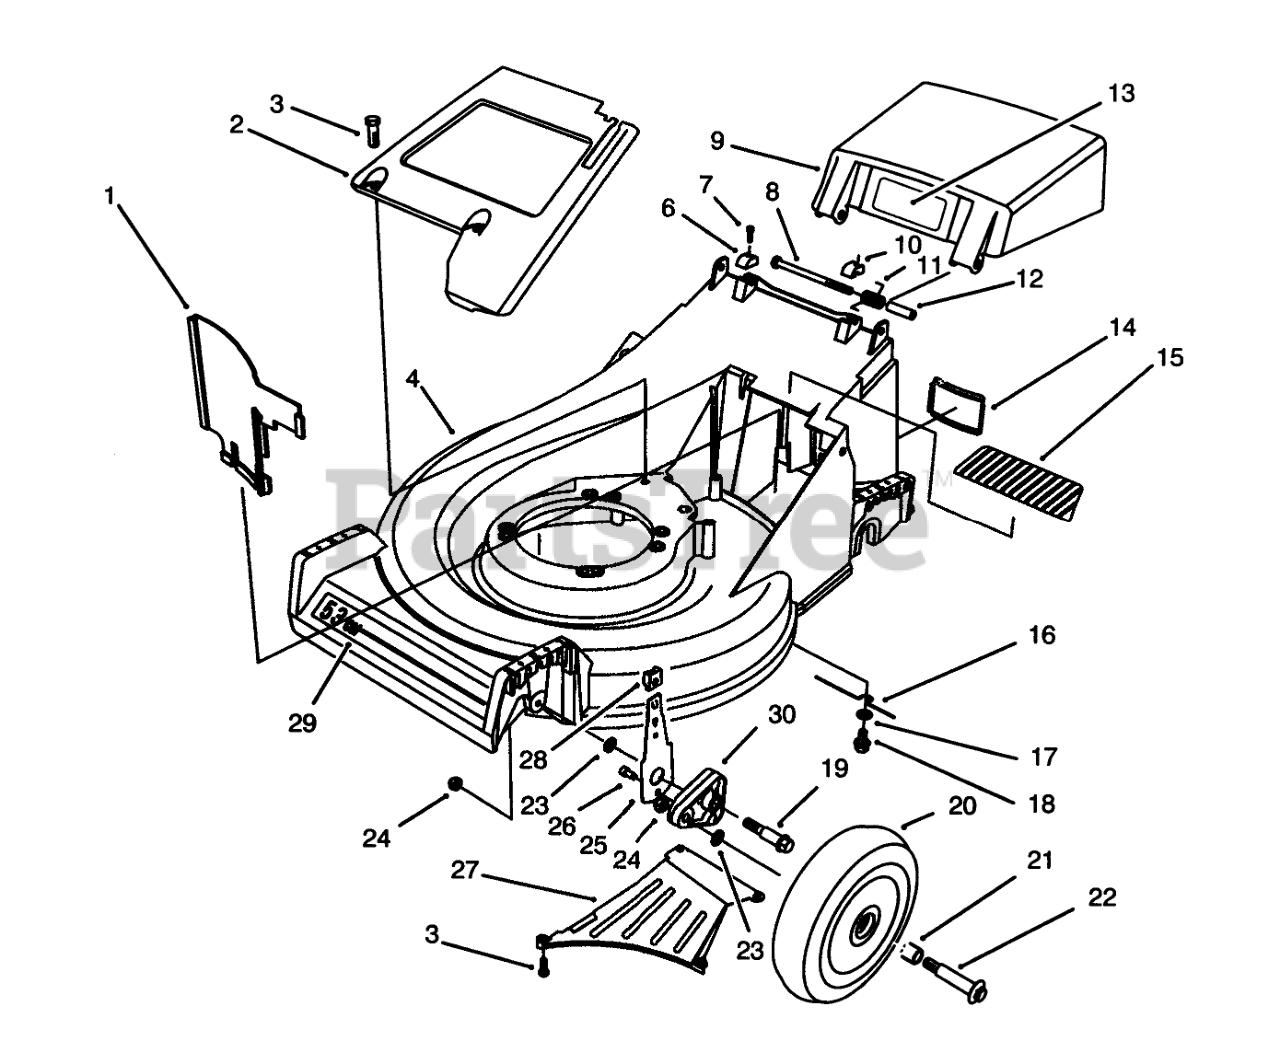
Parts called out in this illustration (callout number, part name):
1	PANEL-VERTICAL
2	PaneI-Screen
3	SCREW-HWHTF
4	Housing-53cm (Incl. Ref. #29)
6	CAP-HINGE BOLT, RH
7	SCREW-HSH
8	SCREW-HH
9	Door Discharge
10	CAP-HINGE BOLT, LH
11	SPRING-DOOR
12	SPACER-DOOR
13	DECAL-DANGER
14	COVER-ACCESS
15	COVER-TOP
16	RETAINER-BELT
17	WASHER-FLAT
18	SCREW-HHFTF
19	BOLT-SHOULDER
20	Wheel & Tire Assembly (Incl. Ref. #21)
21	BUSHING
22	WHEEL BOLT
23	WASHER
24	NUT-LOCK
25	FRONT SPRING ARM ASM
26	SCREW-HSH, THREAD FORMING
27	Ramp-Discharge
28	KNOB-ARM
29	DECAL
30	ARM-PIVOT, FRONT
